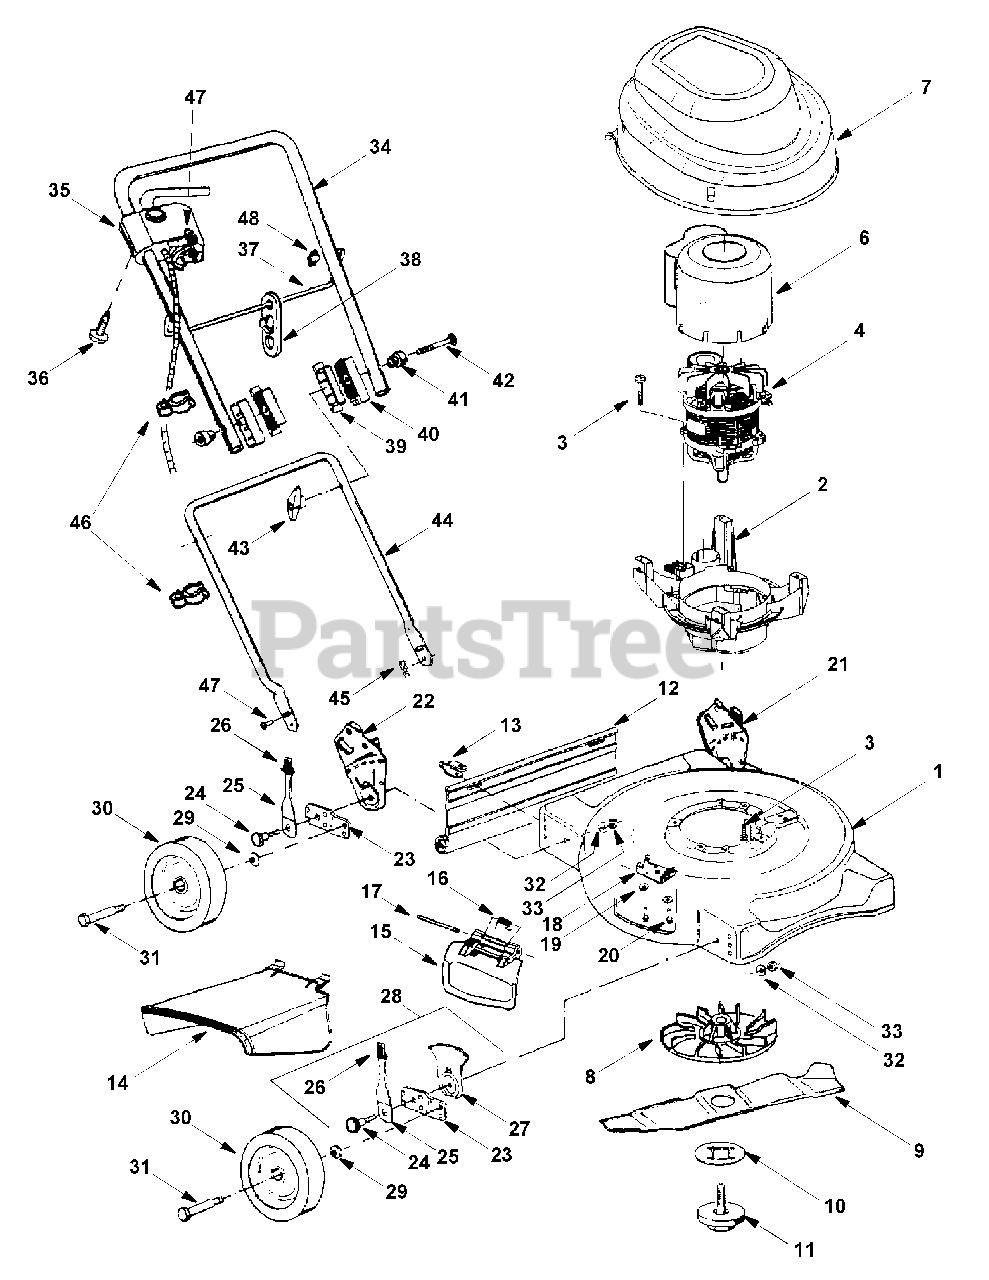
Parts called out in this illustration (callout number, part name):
2	Motor Support
3	Screw
4	Electric Motor 115V, 1500W
6	Air Guide Cover
8	Blade Hub Assembly
9	Mulching Blade
10	Locking Plate
11	Screw, Blade
12	Rear Flap.
13	Hinge Clip
14	Side Discharge Deflector
15	Mulch Plug
16	Torsion Spring
17	Hinge Pin
19	Bell. Washer .265 ID X .75 OD X .062
20	Hex Wash S-Tapp Scr 1/4-20 X .50
21	Handle Bracket Ass’y LH
22	Handle Bracket Ass’y RH
24	Shoulder Screw .50 Dia.
25	Spring Lever Ass’y w/knob
26	Knob
27	Height Adjuster Plate
28	Height Adj. Ass’y RH (w/knob)
28	Height Adj. Ass’y LH (w/knob)
29	Bell. Washer .375 ID X .870 OD X .063
30	Wheel Assembly 8 X 1.8
31	Axle Bolt
32	Bell. Washer .38 ID X 1.38 OD X .06
33	Hex Nut 3/8-16 Gr. 2
36	Screw
37	Guide Rod
38	Cord Restraint
39	Lower Handle Insulator
40	Upper Handle Insulator
41	Insulator Knob
42	Carriage Bolt 5/16-18 x 3.00
43	Wing Nut
46	Cable Guide
47	Mach. Scr. 1/4-20 x .75
48	Wing Nut
